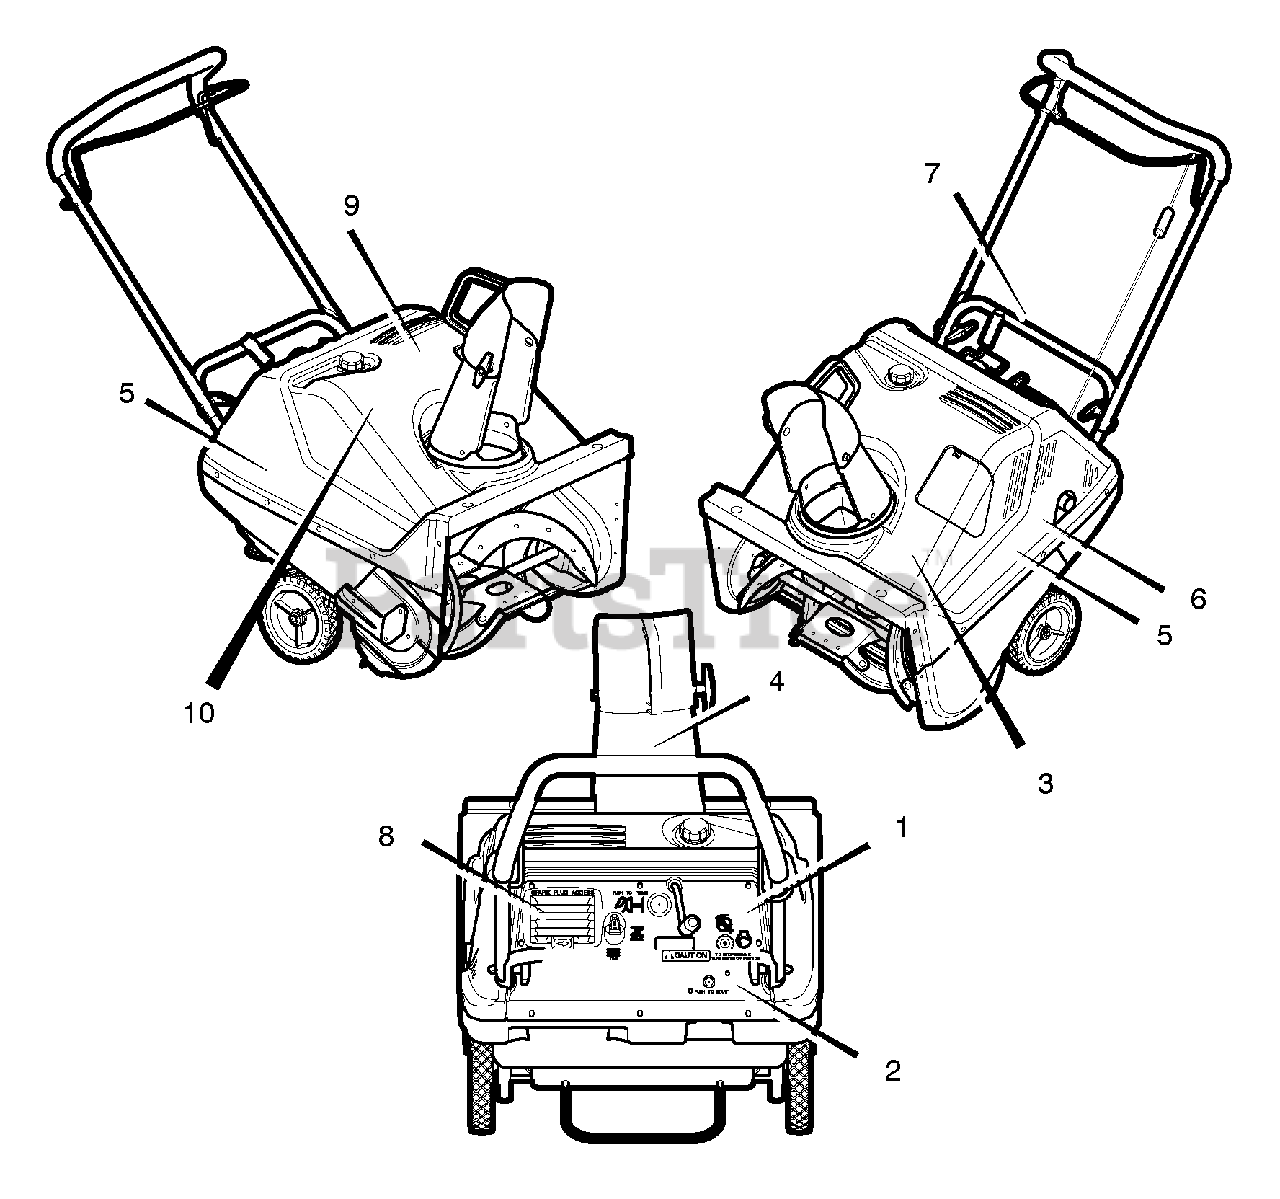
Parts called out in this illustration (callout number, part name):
1	Decal, Control Panel
2	Decal, Electric Start Cover
3	Decal, Danger Auger
4	Decal, Danger Chute
5	Decal, STIGA
6	Decal, Hot Muffler
7	Decal, Auger Control
8	Decal, Spark Plug Access
9	Decal, Snow Breeze
10	Decal, Briggs & Stratton
